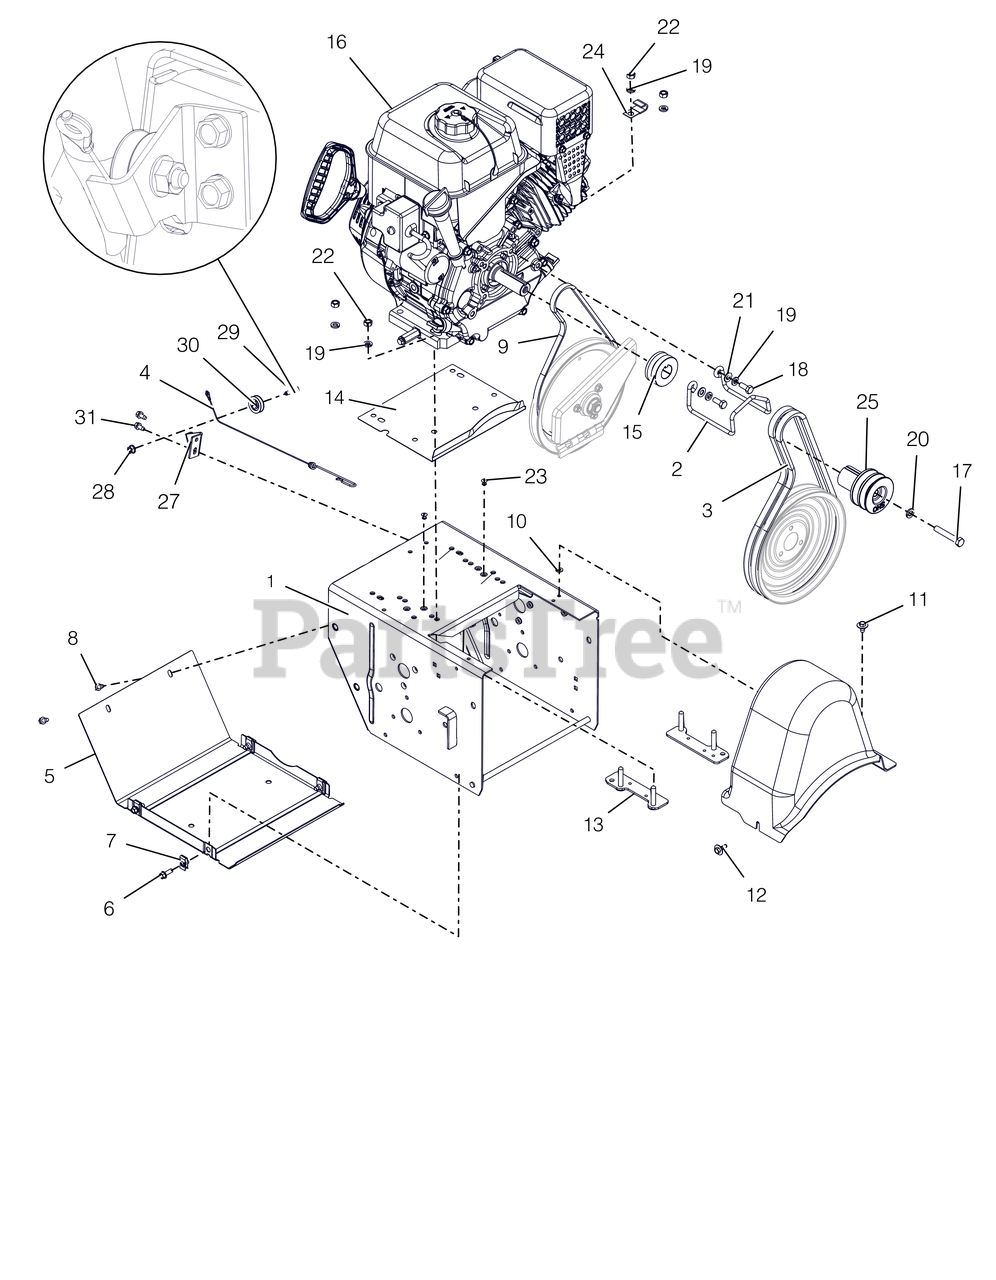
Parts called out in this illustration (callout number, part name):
1	FRAME, MAIN-DELUXE(WELDMENT)
2	FINGER, BELT
3	V-BELT, HA-RAW EDGE (SET)
4	CABLE, LOWER TRACTION,SS & PRO
5	COVER, BOTTOM
6	BLT-HEX .25-20X.75 HWH YZ GR5
7	NUT-RTNR .25-20X.56
8	SCR-TAP .25-20X.50 HWH TR YWZ
9	V-BELT, 3L-WRAPPED
10	NUT-PUSH .25X.50 O.D.
11	SCR-TAP .25-20X.50 LGHWH TR YZ
12	SCR-TAP .25-20X.5 CAPTIVE
13	STRAP, ENGINE-MEDIUM BLOCK
14	BAFFLE, WATER - LARGE BLOCK
15	SHEAVE, DRIVE
16	ENGINE, ARIENS AX291 240V/60W
17	BLT-HEX .38-24X2.25 YWZC GR5
18	BLT-HEX .31-24X.75 YWZC GR5
19	WSHR-LK .312X.097 HVY YWZC
20	@WSHR-LK .38X.094 REG YWZC
21	@WSHR-FL-STL.344X.688X.065YWZC
22	@NUT-HEX .31-18 YWZC
23	RVT-POP .187 YZ
24	J-CLAMP
25	SHEAVE,ATTACHMENT-SHO 2 GRV
27	BRACKET, CABLE PULLEY
28	@NUT-LK-TOP-FLG .25-20 YWZC
29	BOLT, SHLDR-.375X.375X.25-20
30	PULLEY, CABLE
31	SCR-TAP .25-20X.50 HWH TR YWZ
